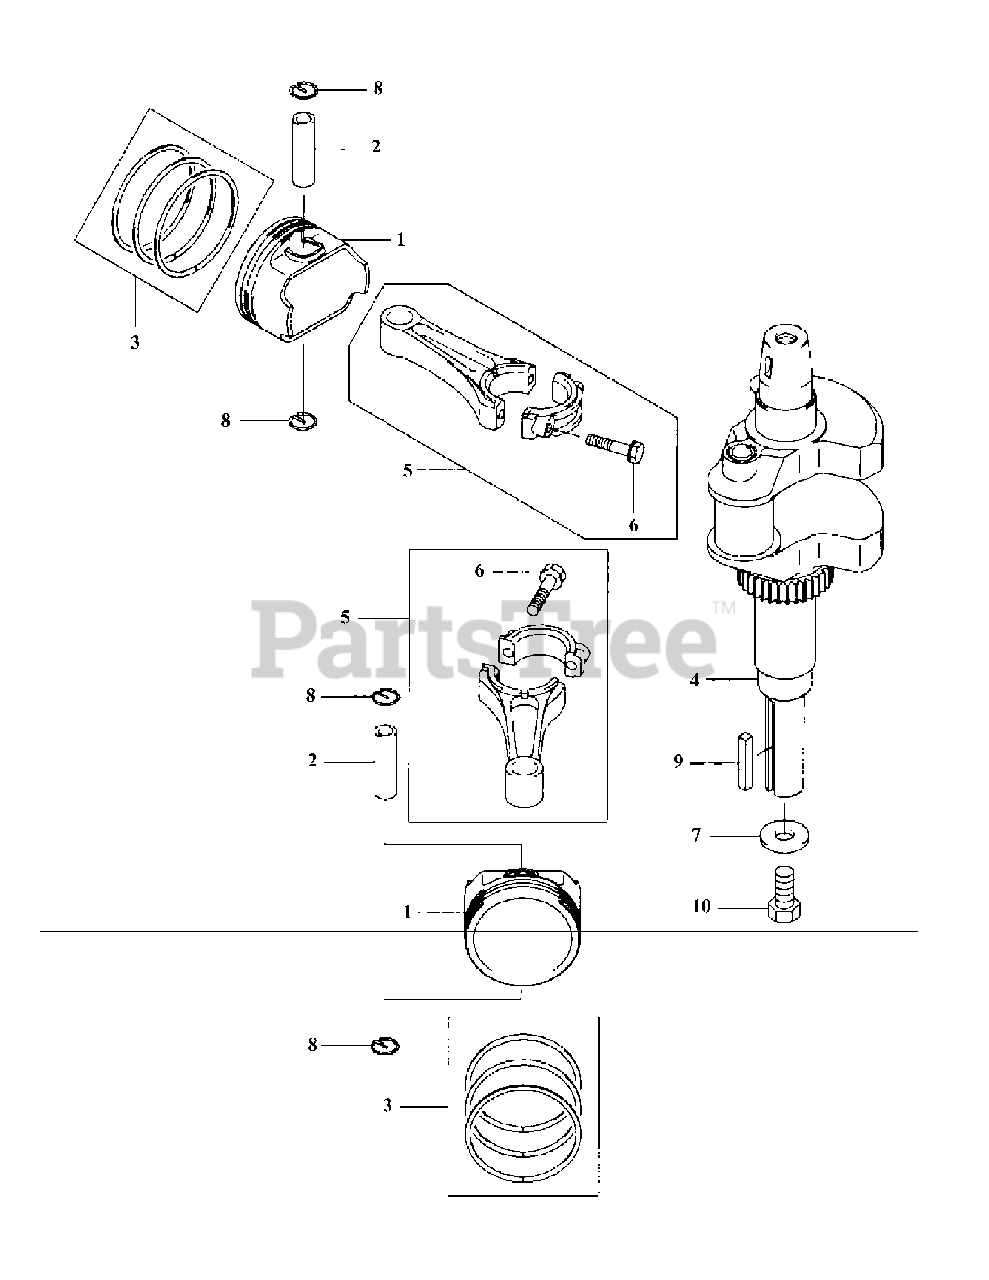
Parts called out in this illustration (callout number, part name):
1	Piston-Engine
1	Piston-Engine 0.50 o/s
3	Ring-Set Piston
3	Ring-Set-Piston 0.50 o/s
4	Crankshaft-Comp
5	Rod-Assy-Connecting
7	Washer, 12.5x32x3.2
10	Bolt,7/16-20unf
